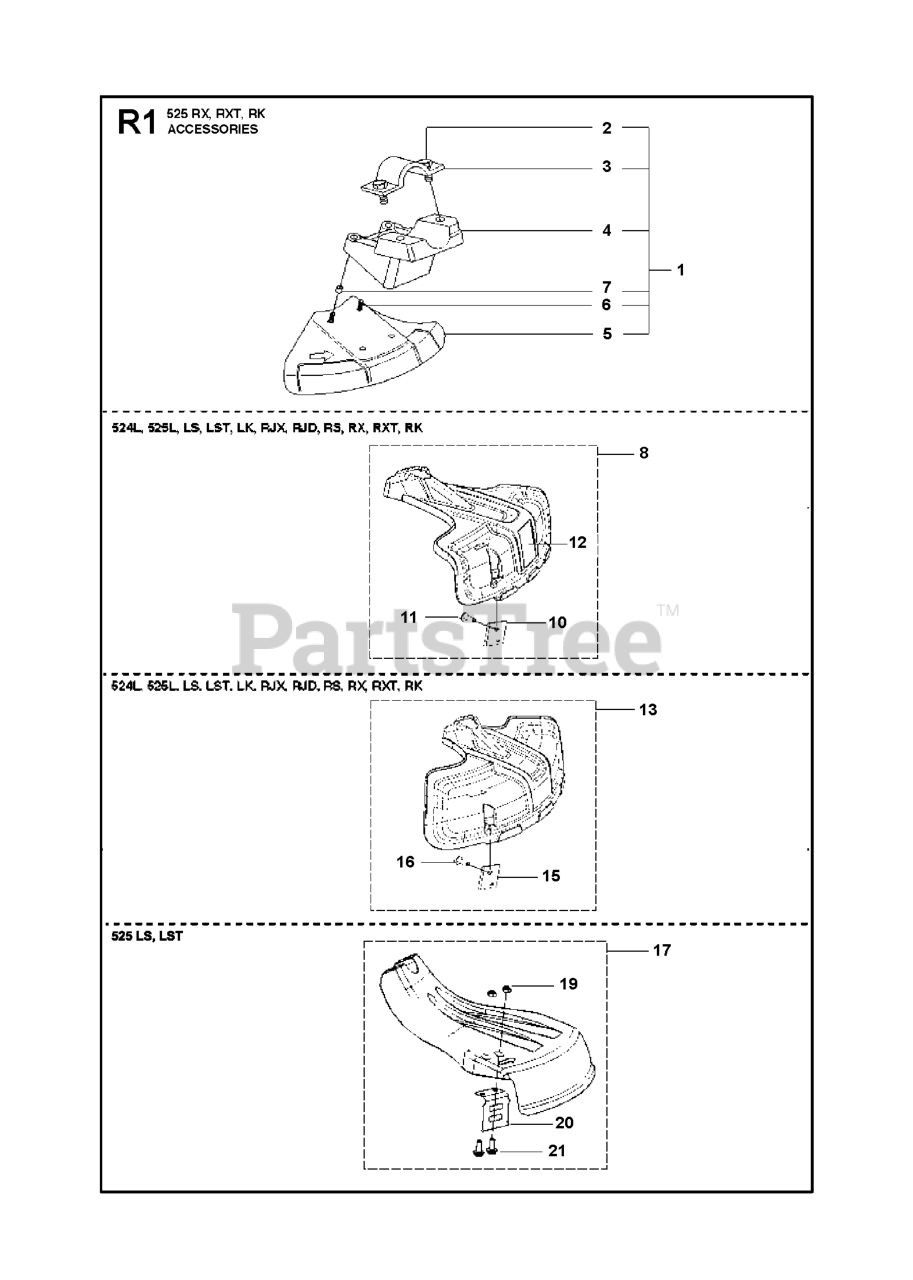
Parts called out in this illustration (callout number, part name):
1	TRIMMER GUARD ASSY
2	SCREW IHSCFMO
3	CLAMP
5	METAL GUARD 200MM
7	LOCKING NUT
8	TRIMMER GUARD 323L MFL.
10	LINE CUTTER
11	SCREW ITXSCFT PW4.8X16 T27 CH
13	COMBINATION GUARD
15	LINE CUTTER
16	SCREW ITXSCFT PW4.8X16 T27 CH
17	GUARD ASSY
